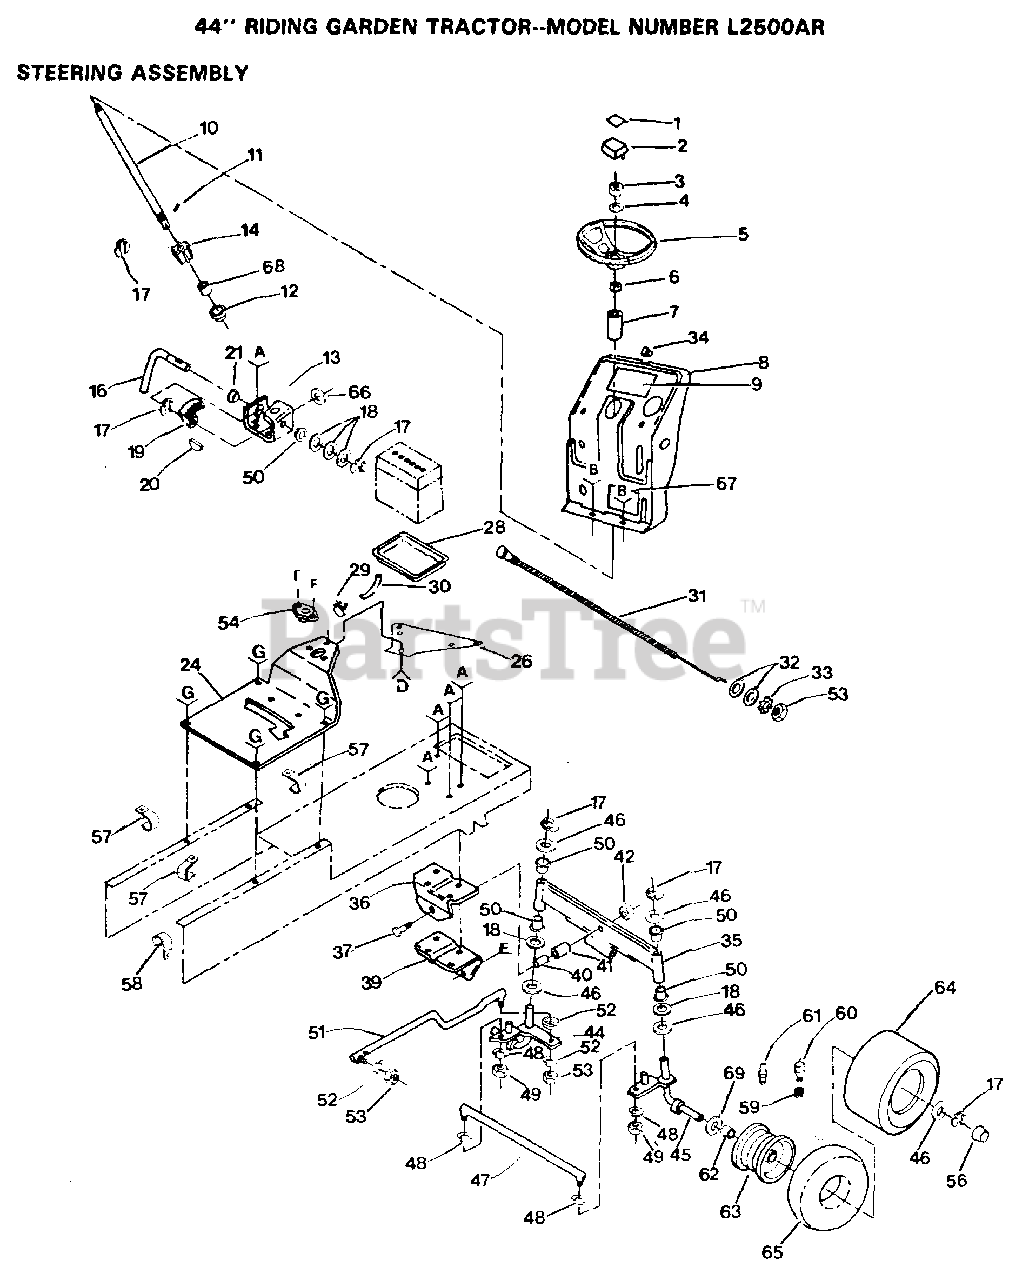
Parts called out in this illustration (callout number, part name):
1	Decal Steering Wheel Insert
2	INSERT-WHEEL LT
3	NUT
4	WASHER
6	ADAPTER LT
7	SLEEVE LTV
10	SHAFT STR HYT
12	BUSHING
14	GEAR PINION T
16	ROD STEERING T
17	RING
18	WASHER .T
19	GEAR.SECTOR.HYT
20	KEY-WOODRUFF LT
21	NYLINER T
28	"TRAY T, BATTERY"
29	HOSE CLAMP T
32	WASHER
33	LOCKWASHER
34	PLUG-DASH T
36	SUPPORT-SADDL T
37	BOLT LT
39	SUPPORT.SADDLE.FT
42	"NUT-LOC,FLANGE LT"
44	SPINDLE LH YT
48	LOCKWASHER
49	NUT
50	COL. SRTG. BEAR.
51	LINK-DRAG LT
52	LOCKWASHER
56	HUB CAP
57	CLIP T
58	INSUL CLIP T
59	VALVE CAP
60	VALVE STEM LT
61	FITTING LT
62	"FLANGE, BEARING"
65	TUBE.5.3/4.5/6
67	DECAL, INSTRUCTION
68	SHAFT SPACER LT
